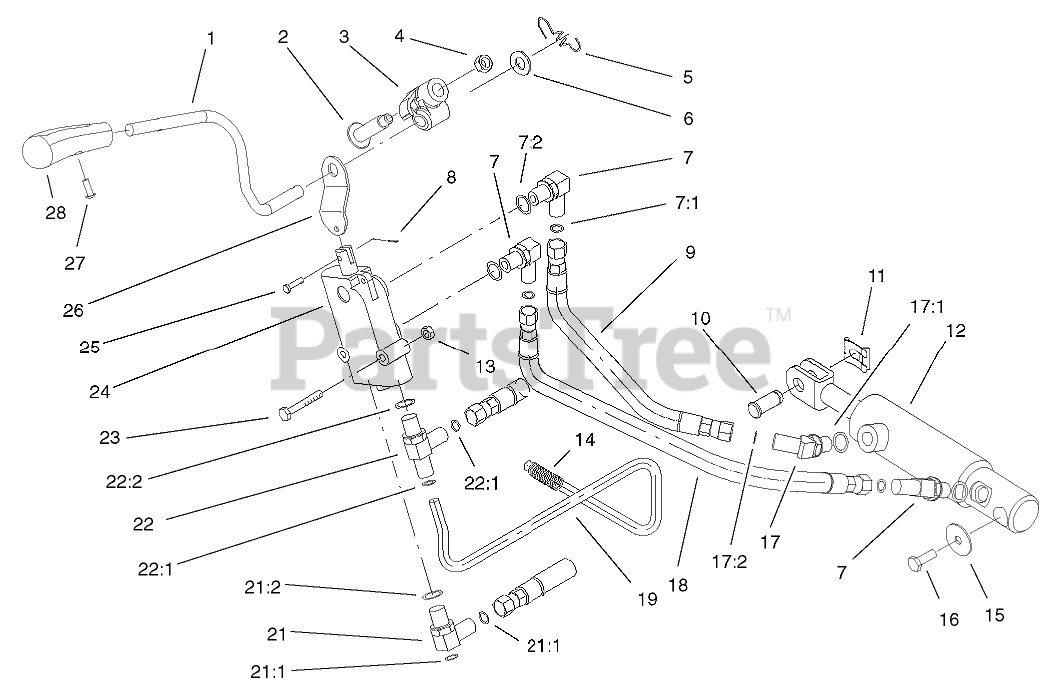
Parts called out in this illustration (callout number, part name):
1	HANDLE-LIFT
2	BOLT-SHOULDER
3	TRUNNION-LEVER, LIFT
4	NUT-JAM, LOCKING
5	SPRING-EXTENSION, LIFT
6	WASHER
7	FITTING-HYD, 90 DEGREE
7:1	O-RING
7:2	O-RING
8	PIN-COTTER
9	HOSE ASM
10	PIN-CLEVIS
11	CLIP-PIN
12	LIFT CYLINDER ASM
13	NUT-LOCK, NI
14	COVER-BRACE
15	WASHER-FLAT
16	SCREW-THREAD LOCKING
17	FITTING-HYD, 45 DEGREE
17:1	O-RING
17:2	O-RING
18	HOSE ASM
19	TUBE-HYD
21	FITTING-HYD, 90 DEGREE
21:1	O-RING
21:2	O-RING
22	FITTING-HYD, TEE
22:1	O-RING
22:2	O-RING
23	SCREW-HH
24	VALVE-HYD
25	PIN-CLEVIS
26	LINK-LIFT
27	SCREW-PPHTF
28	Knob-Lift (only on: 73552)
28	Knob-Lift (only on: 73590)
